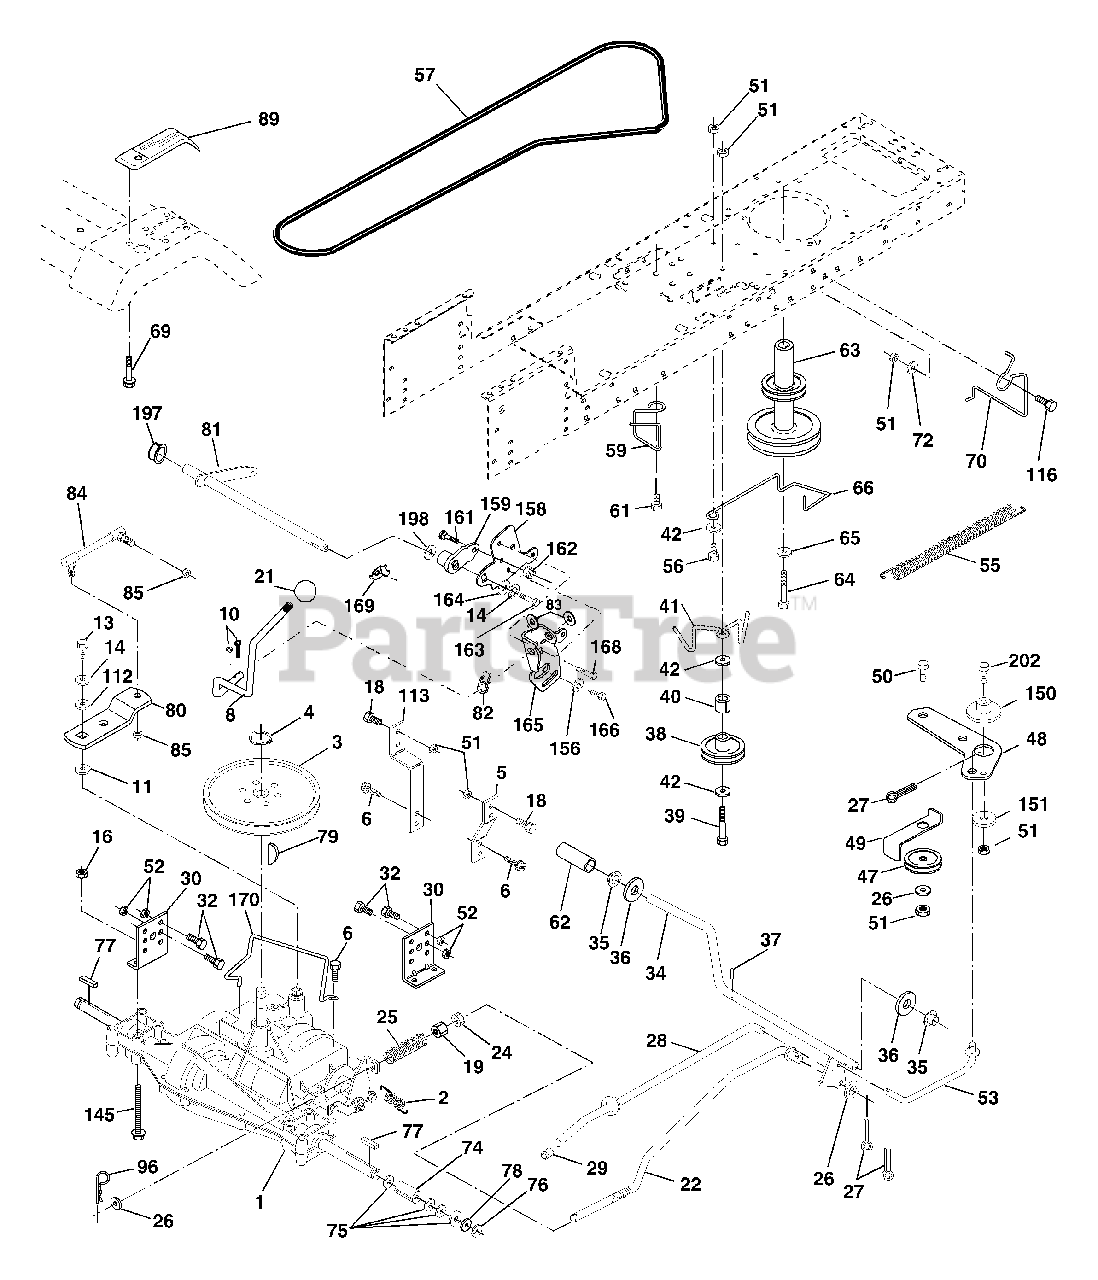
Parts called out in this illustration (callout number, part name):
2	Spring Return Brake T/a Zinc
3	Pulley Transaxle 18" tires
4	Ring Retainer # 5100-62
5	Strap Torque 30 Degrees
6	Screw 5/16-18 X 3/4
8	Rod Shift Fender Adjust Lt
10	Pin Cotter 1/8 X 1 Cad
11	Washer Plate Shf 388 Sq Hole
13	Bolt 1/4-28 Unf Gr 8 W/Patch
14	Washer Lock Hvy Helical
16	Nut Lock Hex w/ins 5/16-18
18	Bolt, Fin Hex 3/8-16 UNC x 1 Gr. 5
19	Nut Lock 3/8-16 Unc
21	Knob
22	Rod Brake Blk Zinc 26 840
24	Nut Hex Jam 3/8-16 Unc
25	Spring Rod Brake 2 00 Zinc
26	Washer 13/32 X 13/16 X 16 Ga
27	Pin Cotter 1/8 X 3/4 Cad
28	Rod Brake Parking LT/YT
29	Cap Brake Parking
30	Bracket Mtg Transaxle
32	Bolt Hex Hd 5/16-18unc X 3/4
34	Shaft Asm Pedal Foot
35	Bearing Nylon Blk 629 Id
36	Washer 21/32 X 1 X 16 Ga
37	Pin Roll 3/16 X 1"
38	Pulley Idler Flat
39	Bolt Fin Hex 3/8-16 unc X 2-3/4
40	Spacer Split 395 X 59 Bzp
41	Keeper Belt Flat Idler
42	Washer 13/32 X 13/16 X 12 Ga
47	Pulley Idler V Groove Plastic
48	Bellcrank Asm
49	Retainer Belt Style Spring
50	Bolt Hex Hd 3/8-16unc X 1-1/2
51	Nut Crownlock 3/8-16 Unc
52	Nut Crownlock 5/16-18 Unc
53	Link Clutch
55	Spring Return Clutch 6 75
56	Bolt Fin Hx 3/8-16 X 1/4
57	V-Belt Ground Drive 95 25
59	Keeper Belt Span Ctr
61	Screw 3/8-16x.75
62	Cover Pedal Blk Round
63	Engine Pulley LT/YT
64	Bolt Hex
65	Washer Lock Hvy Hlcl Spr 7/16
66	Keeper Belt Engine Foolproof
69	Screw Hex wsh Hi Lo 1/4 x 1/2 unc
70	Guide Belt Mower Drive RH
72	Washer 13/32 X 1-1/4 X 12 Ga
74	Spacer Axle
75	Washer 25/32 X 1 1/4 X 16 Ga
76	E-ring #5133-75
77	Key Square 2 0 X 1845/ 1865
78	Washer 25/32 X 1-5/8 X 16 Ga
79	Key Woodruff #9 3/16 x 3/4
80	Arm Shift
81	Shaft Asm Cross Tapered PMST/20
82	Spring Torsion T/a
83	Washer 17/32 X 3/4 X 16 Ga
84	Link Transaxle PMST/20" Zinc
85	Nut Lock Center 1/4 - 28 FNTHD
89	Console Shift STLT
96	Retainer Spring 1"
112	Washer 9/32 x 3/4 x 10 Ga.
113	Strap Torque LT
116	Bolt Rdhd Sq Neck 3/8-16 x 1.25
145	Bolt Hex FLGHD 5/16-18 Gr. 5
150	Bushing Bellcrank
151	Washer 13/32 x 2 x 10
156	Washer Srrted 5/16ID x 1.125
158	Bracket Shift Mount
159	Hub Tapered Flange Shift Lt
161	Bolt Rdhd Sqnk 1/4-20 x 3/4 Gr
162	Nut Crownlock 1/4-20 Unc
163	Bolt Hex Fin 1/4-20 Unc x 1 Gr 5
164	Washer 5/8 x .281 x 10 Ga
165	Bracket Pivot Lever
166	Screw 5/16-18 x 5/8
168	Bolt Shoulder 5/16-18 x .561
169	Plate Fastening
170	Keeper Belt Transaxle Gear
197	Nyliner Snap-In
198	Washer Nyliner
202	Bolt Carr Sh 3/8-16 x 1-1/2 Gr. 5
